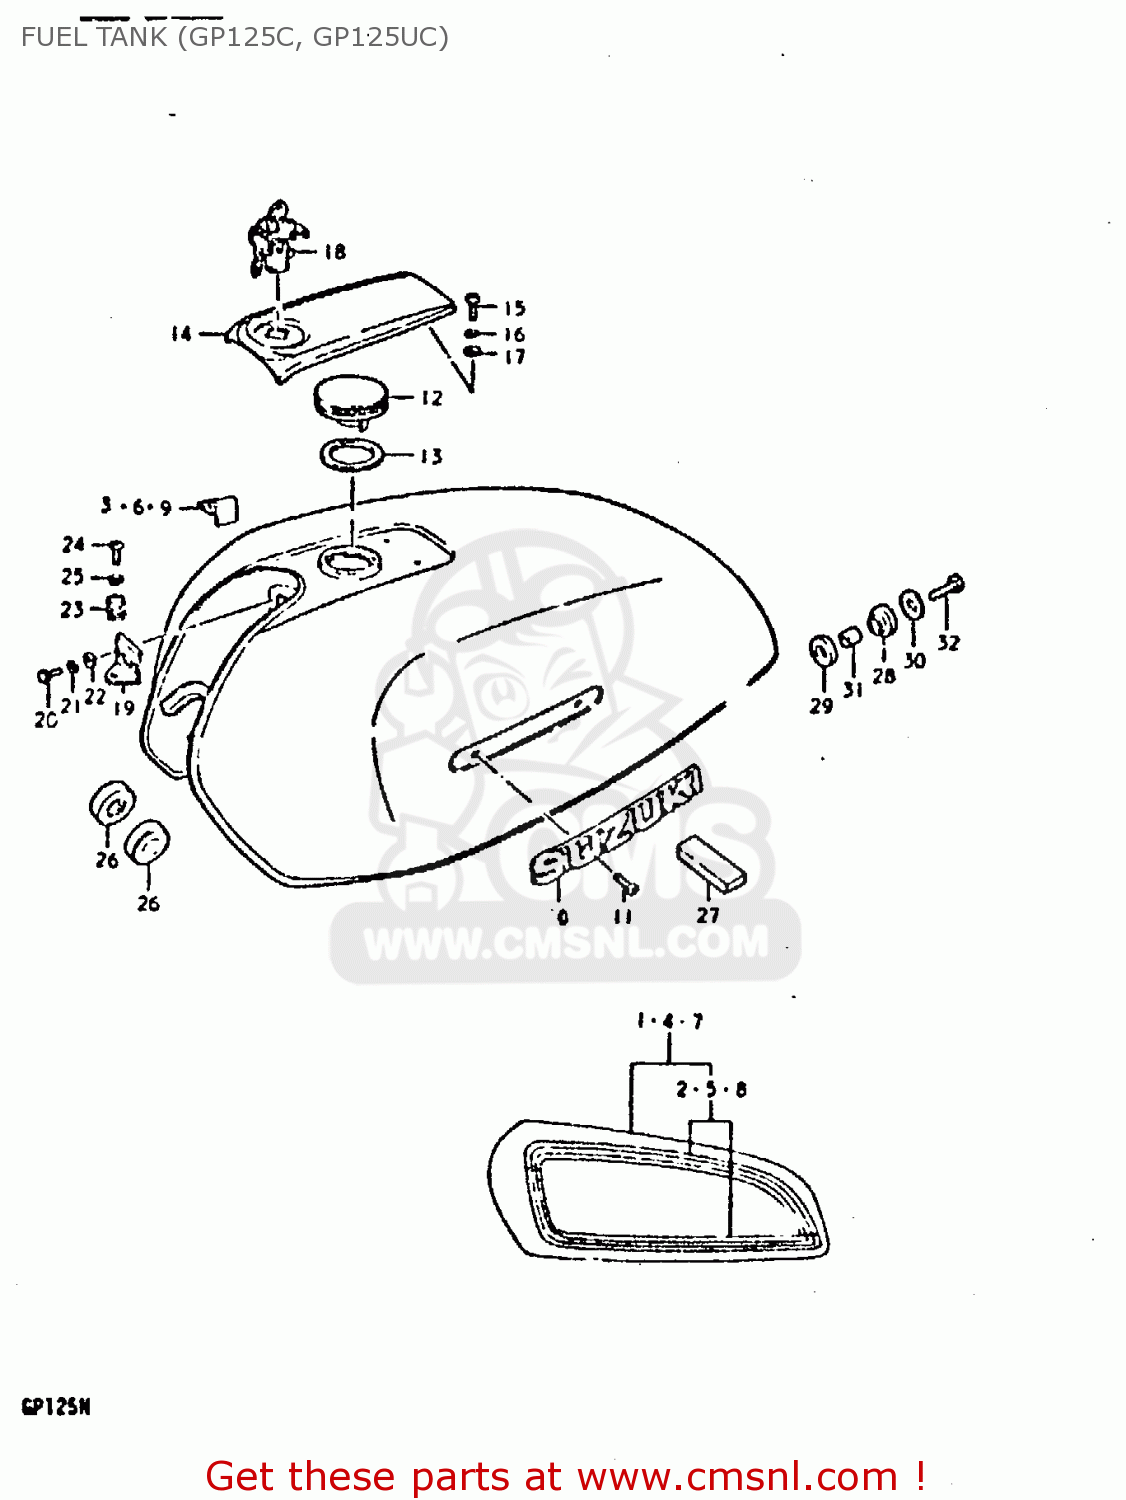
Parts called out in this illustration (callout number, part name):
1	TANK, FUEL
2	TAPE SET
3	CUSHION,FUEL TANK FR COVER
10	EMBLEM,FUEL TANK
11	SCREW
12	CAP,FUEL TANK
13	GASKET (NAS)
14	COVER,FUEL TANK FR
15	BOLT
16	LOCK WASHER
17	WASHER
18	LOCK,FUEL TANK FR COVER
19	HOLDER,FUEL TANK FRONT COVER
20	BOLT
21	LOCK WASHER
22	WASHER
23	SPRING
24	SCREW
25	LOCK WASHER
26	CUSHION
27	CUSHION
28	CUSHION
29	CUSHION
30	WASHER (8.5X29X1.6)
31	SPACER (8.2X12X17)
32	BOLT (8X30)
